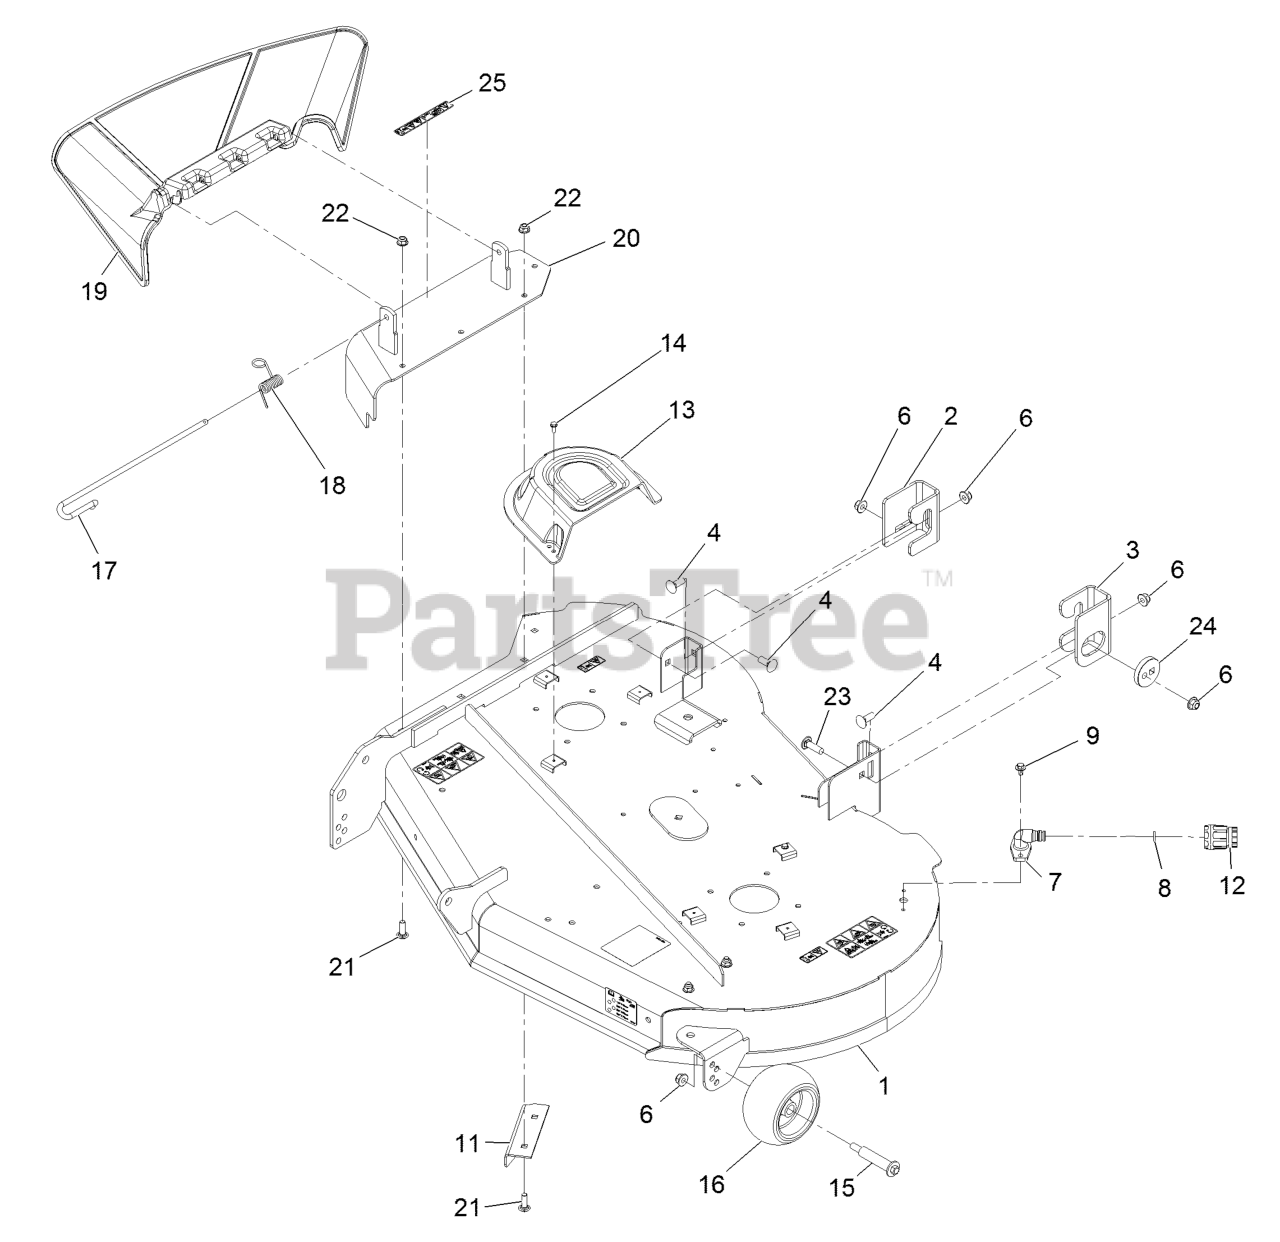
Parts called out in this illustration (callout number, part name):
1	42" DECK AND DECAL ASM (S
3	BRACKET-HANGER, LH
4	BOLT-CARR
6	NUT-HF, NI
9	SCREW-HHFTF
11	BAFFLE-CUTOFF
12	CONNECTOR-HOSE
13	COVER-BELT
14	SCREW-TAPTITE
15	BOLT-SHOULDER
16	ROLLER-SCALP, ANTI
17	PIN-CHUTE
18	SPRING-TORSION
19	DEFLECTOR-DISCHARGE
20	DISCHARGE COVER ASM
21	SCREW-CARR
22	NUT-HF, NI
23	Bolt-Carriage 3/8-16 X 1 1/4
24	ECCENTRIC
25	DECAL-DANGER
